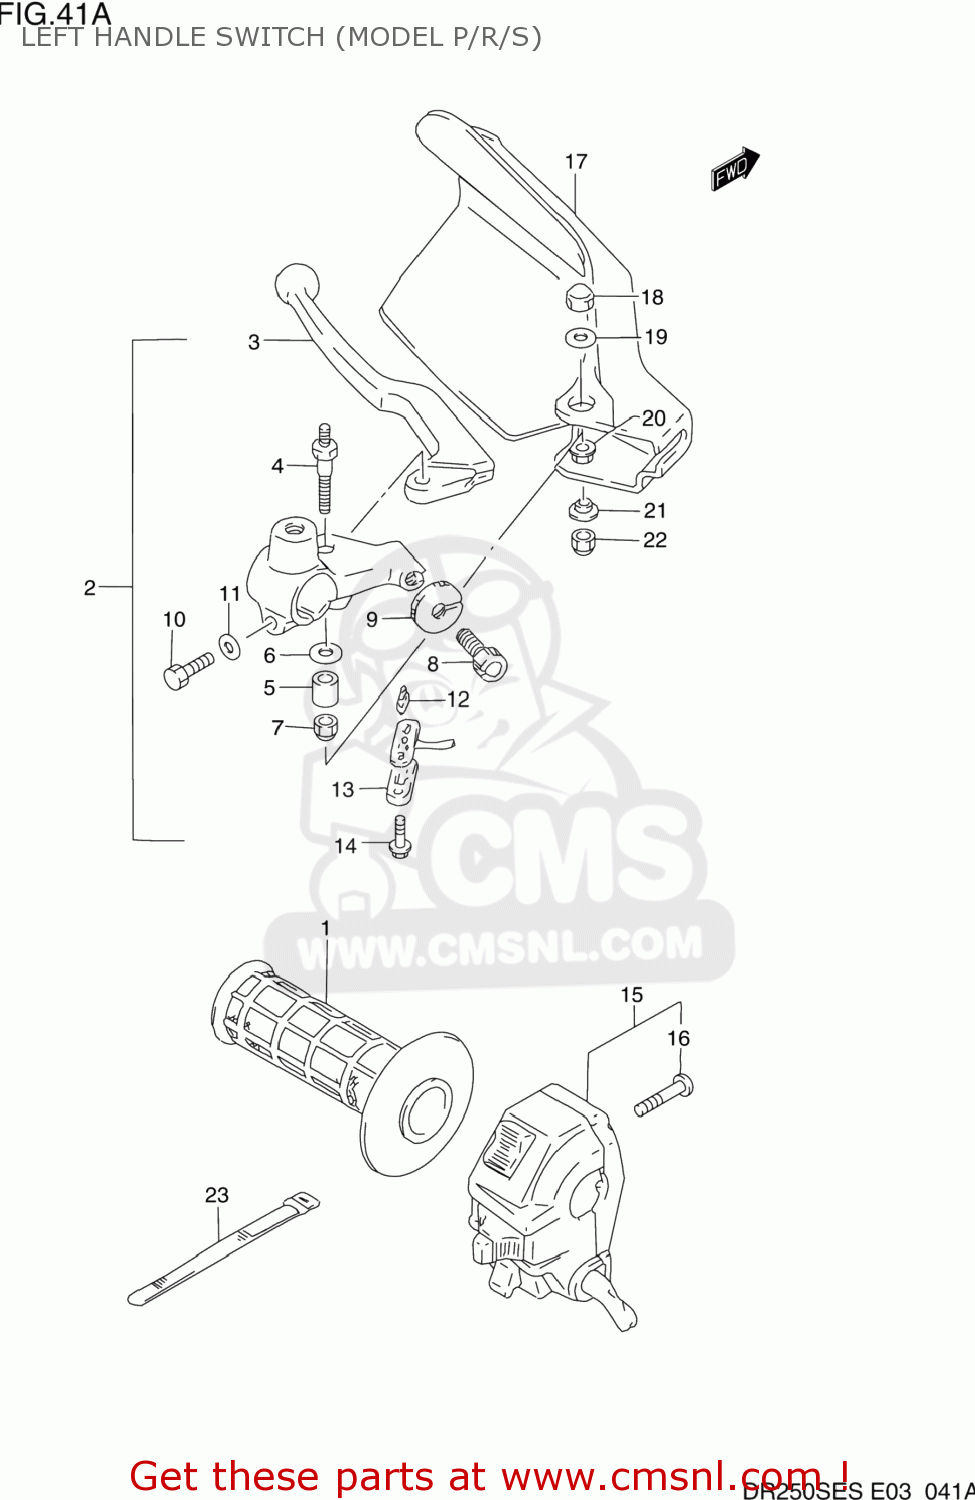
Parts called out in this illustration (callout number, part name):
1	GRIP,L
2	LEVER ASSEMBLY
3	LEVER,CLUTCH
4	BOLT,LEVER SET
5	SPACER,LEVER SET
6	WASHER,LEVER SET
7	NUT
8	ADJUSTER,CABLE
9	NUT,LOCK
10	BOLT
11	WASHER
12	CONTACT,SWITCH
13	COVER,FR BK TERMINAL BASE
14	SCREW
15	SWITCH ASSEMBLY,HANDLE,LEFT
16	SCREW
17	COVER,KNUCKLE,LEFT
18	NUT
19	WASHER(6.5X20X1.6)
20	WASHER(6.5X16X1.2)
21	WASHER
22	NUT 6MM
23	CLAMP(L:120)
